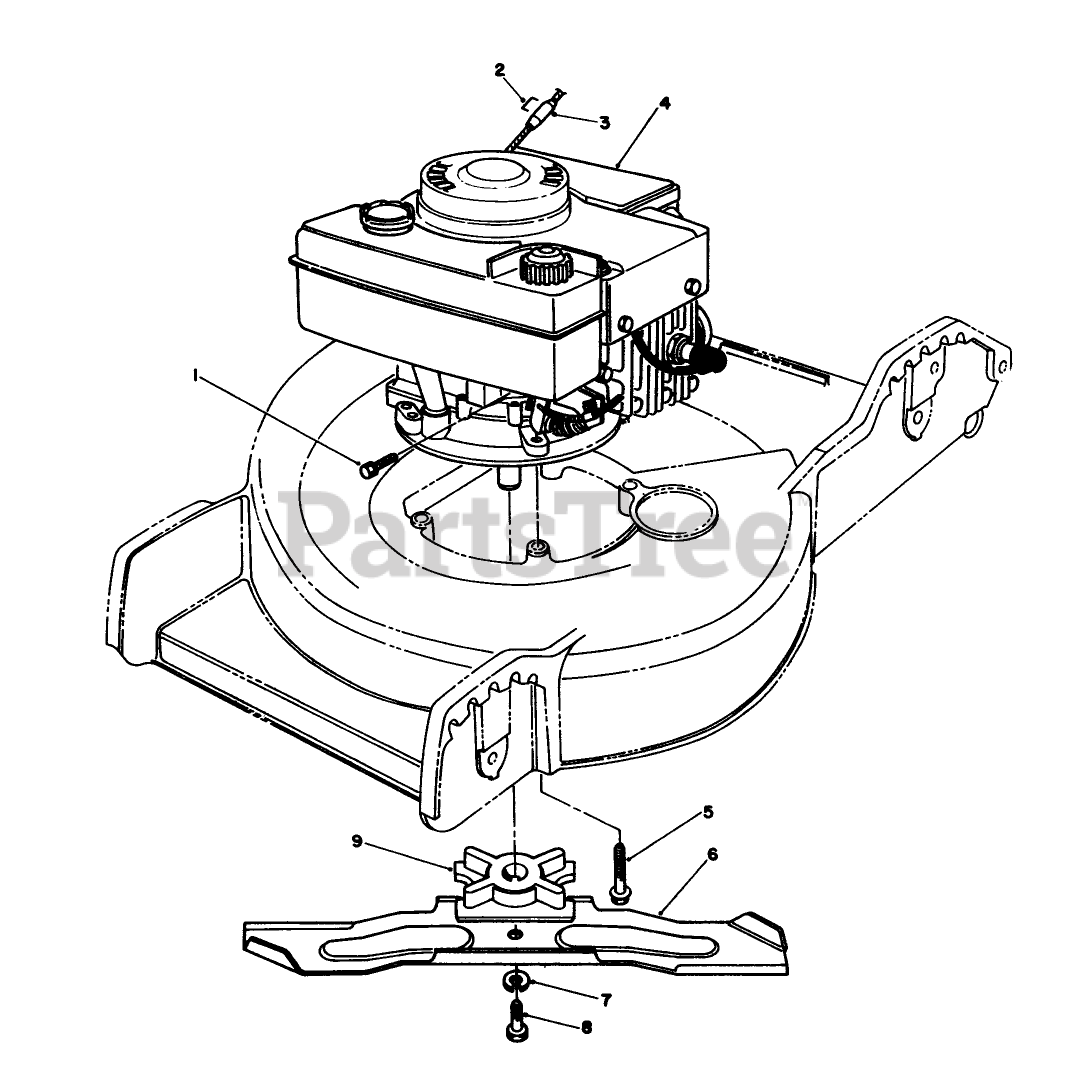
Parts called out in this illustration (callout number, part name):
1	SCREW-HH
2	Staple
3	Stop-Rope
5	3/8-16 X 2 CAPSCREW
6	Blade
7	WASHER-LOCK
8	SCREW-HH
9	BLADE RETAINER
